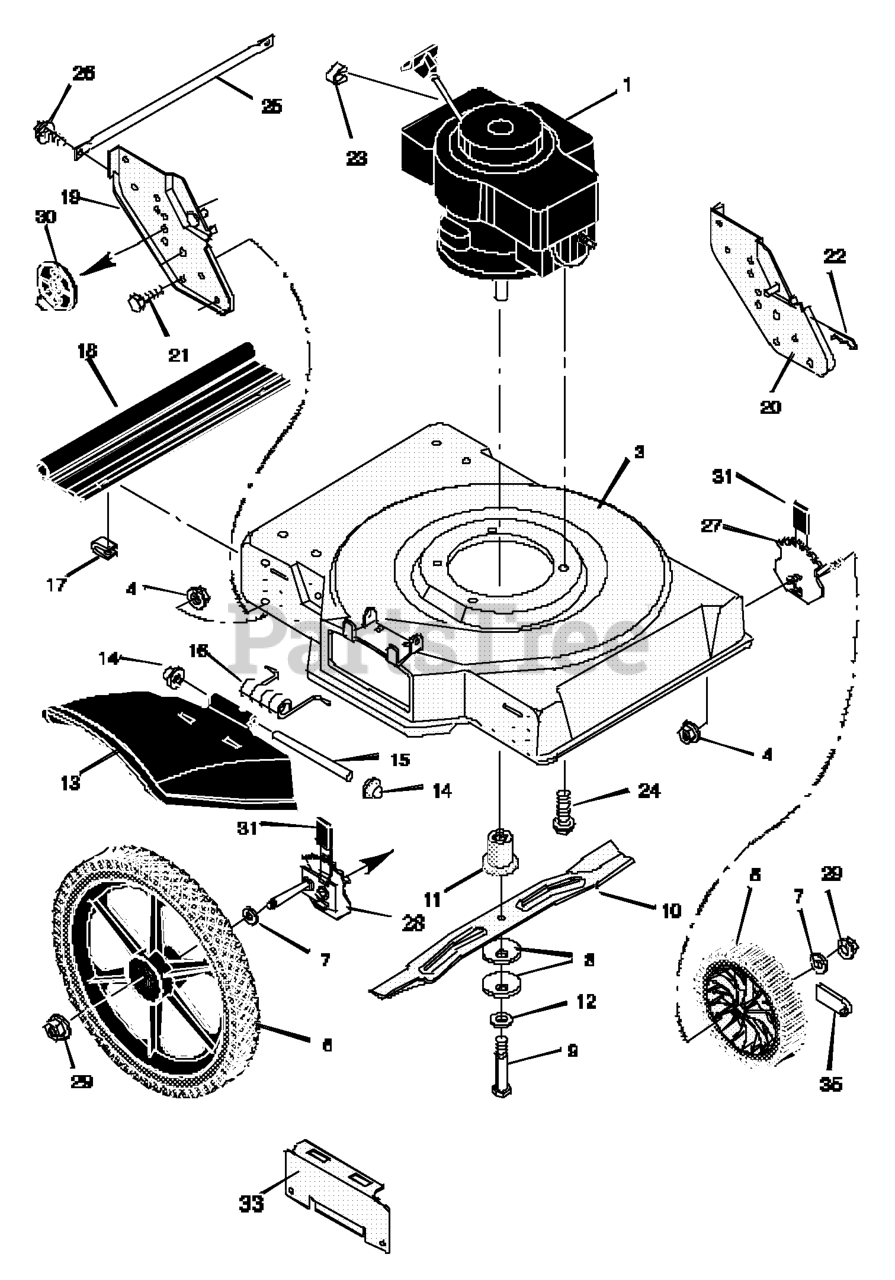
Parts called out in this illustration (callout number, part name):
1	Engine *
3	Housing
4	Nut, Hex
5	Wheel and Tire, Front *
6	Wheel and Tire, Rear *
8	Washer, Blade
9	Bolt, Hex
11	Blade Adapter
13	Deflector, Chute
14	Push On Cap
15	Pin, Pivot
17	Retainer
18	Deflector, Rear
19	Bracket, Right Wheel
20	Bracket, Left Wheel
21	Bolt, Hex
22	Pin, Hair
23	Stop, Rope
24	Bolt, Engine
27	Height Adjuster, Front
28	Height Adjuster, Rear
29	Locknut
33	Plate, Mulching
35	Hub Cap
